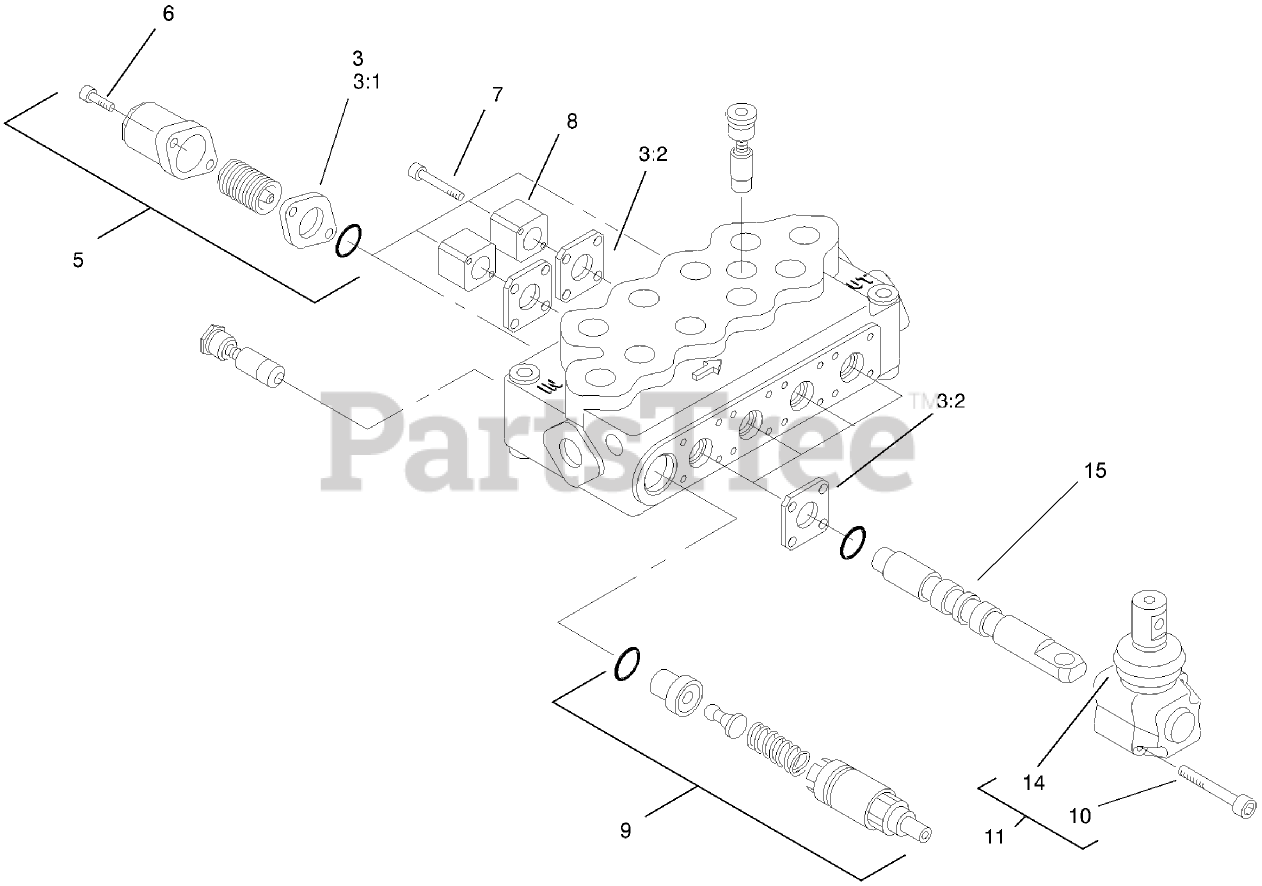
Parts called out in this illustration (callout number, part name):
3	SEAL KIT
3:1	GASKET
3:2	GASKET
5	HIGH FORCE SPRING KIT
6	SCREW-CAP, END
8	BLOCK-MOUNT, SWITCH
9	VALVE-RELIEF
11	OPERATOR ASM
15	SPOOL-VALVE
